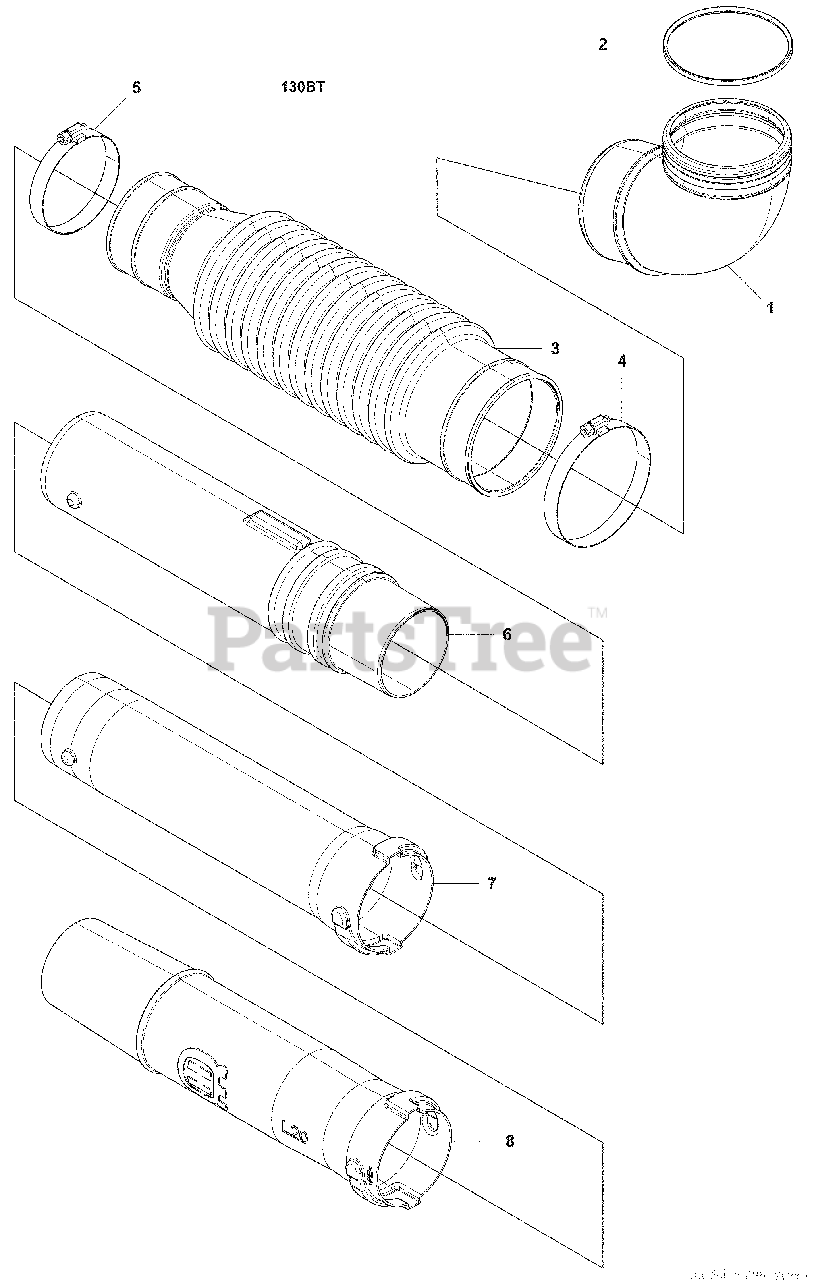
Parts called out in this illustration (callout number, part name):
2	O-Ring
5	Clamp, F96
6	Swivel Joint Tube
7	Middle Tube
